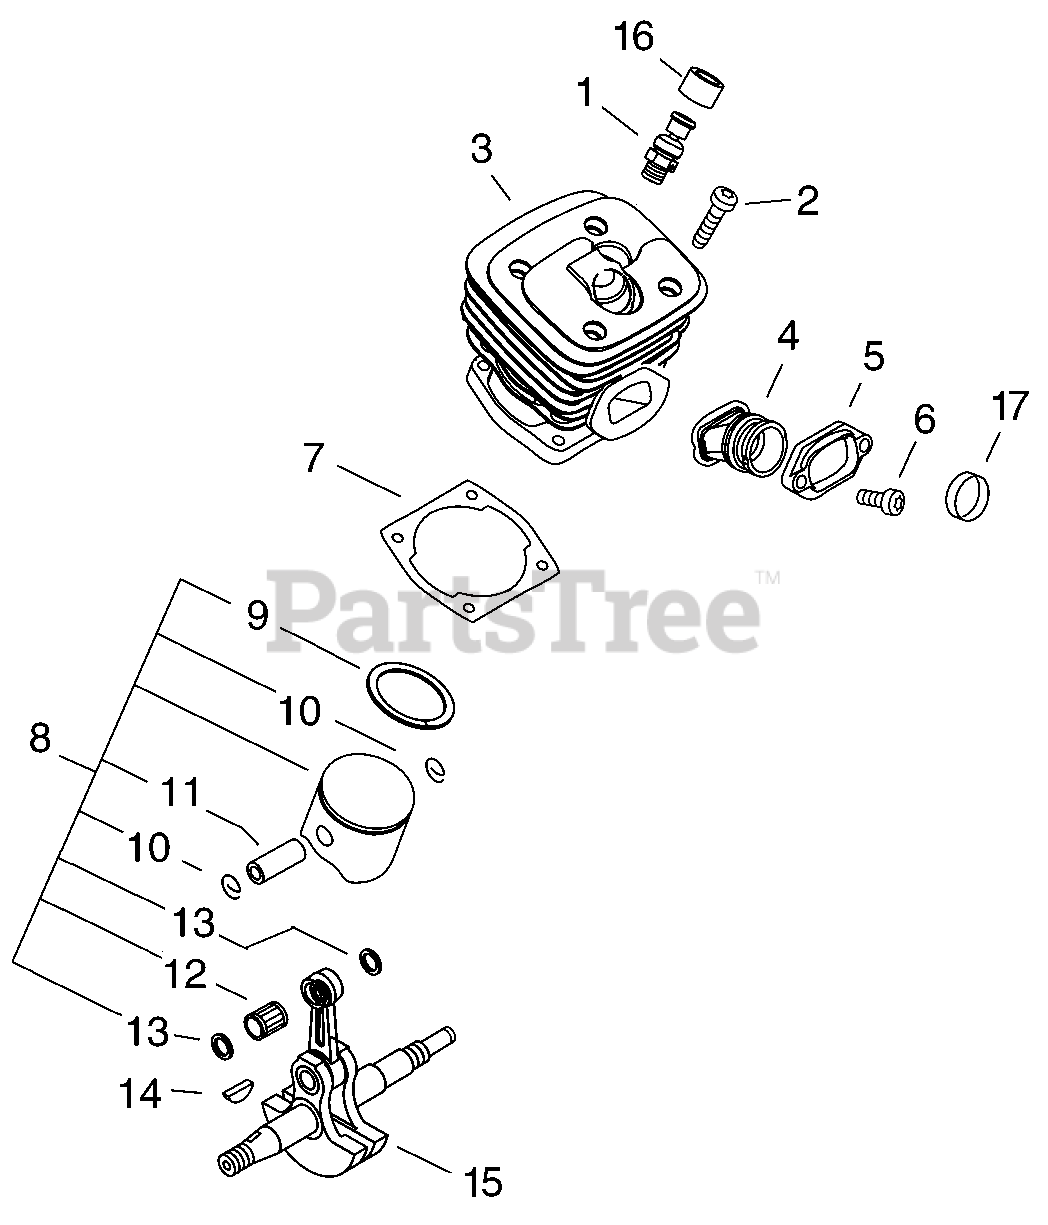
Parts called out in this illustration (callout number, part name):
1	VALVE ASSY, DECOMPRESSION
2	BOLT, TORX 5×25
3	CYLINDER
4	BELLOWS, INTAKE
5	HOLDER, BELLOWS
6	BOLT, TORX 5×16
7	GASKET, CYLINDER
8	PISTON KIT
9	RING, PISTON
10	RING, SNAP Ø11
11	PIN, PISTON
12	BEARING, NEEDLE 11
13	WASHER, THRUST
14	KEY, WOODRUFF
15	CRANKSHAFT ASSY
16	COVER, DUST
17	COLLAR 18.6×20.4×4
